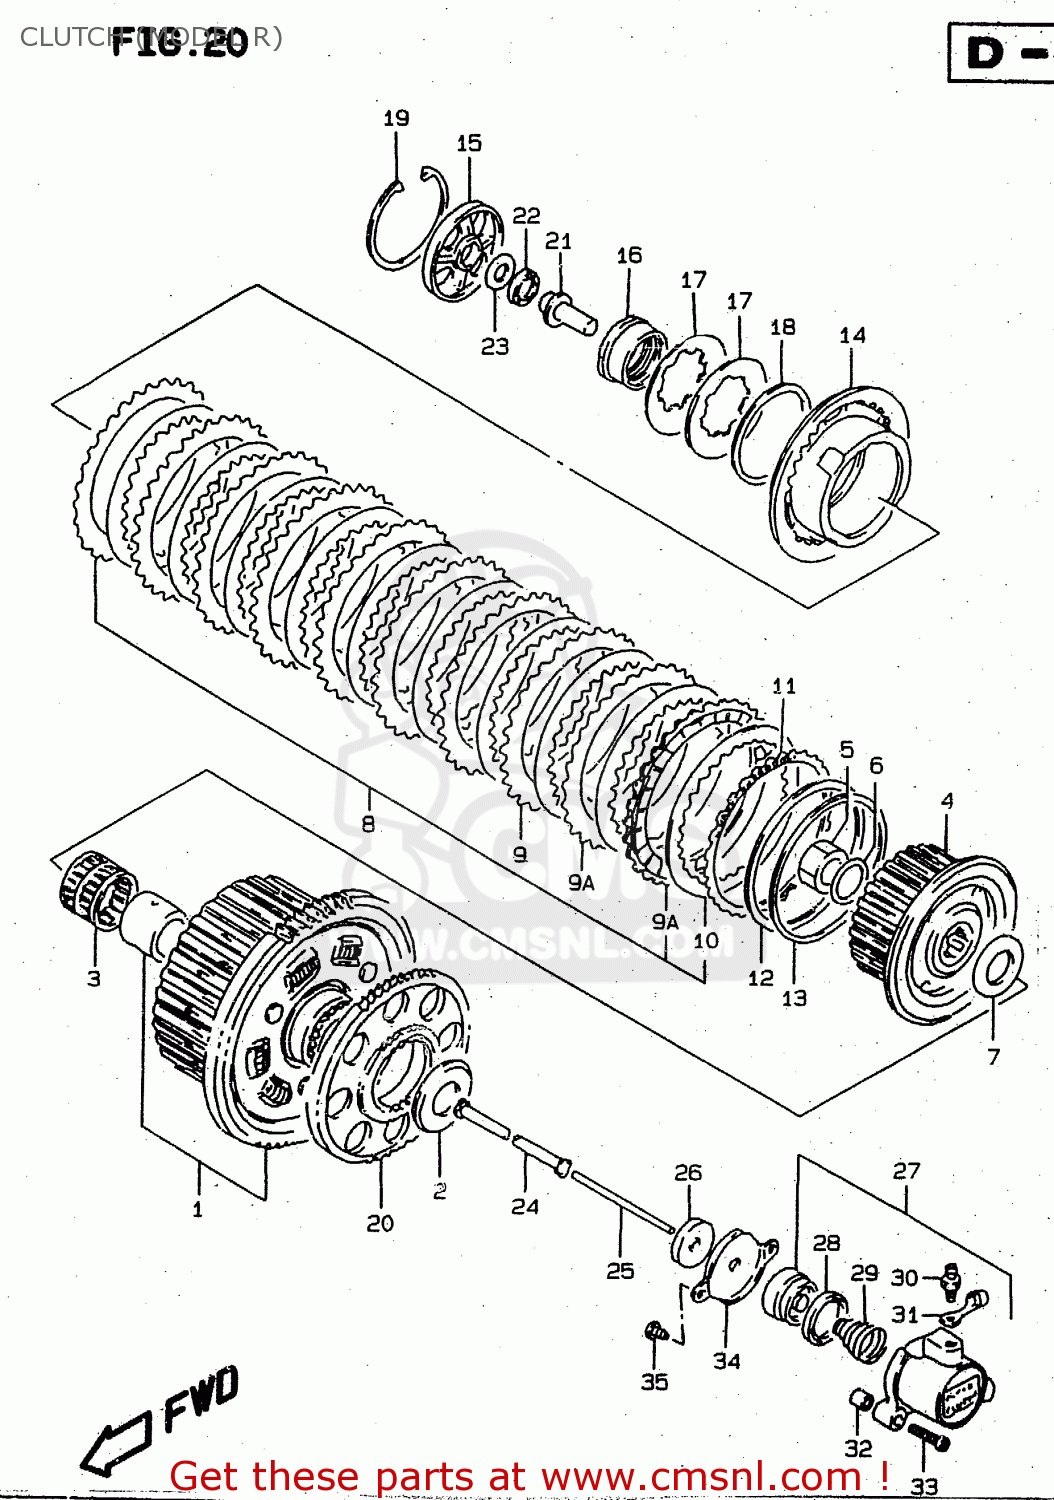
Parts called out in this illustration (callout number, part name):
1	GEAR ASSEMBLY,PRIMARY DRIVE
2	WASHER(25X54X2.5)
3	BEARING(35X40X35.8)
4	HUB,CLUTCH SLEEVE
5	NUT
6	WASHER
7	WASHER(25X50X2.5)
8	PLATE ASSY,CLUTCH
9	PLATE,CLUTCH DRIVE NO.1 (NAS)
9A	PLATE,CLUTCH DRIVE NO.2 (NAS)
10	PLATE,CLUTCH DRIVEN (NAS)
11	PLATE,CLUTCH DRIVE NO.2
12	WASHER
13	SEAT,CL SLEEVE HUB WAVE WASHER
14	DISC,CLUTCH PRESSURE
15	LIFTER,CLUTCH PRESSURE DISC
16	HOLDER,CLUTCH SPRING
17	WASHER
18	SEAT,CLUTCH SPRING
19	CIRCLIP
20	GEAR,GENERATOR DRIVE
21	PIECE,CLUTCH PUSH
22	BEARING(15X28X2)
23	WASHER(15.5X28X1)
24	ROD,CLUTCH
25	ROD,CLUTCH PUSH,L
26	SEAL,OIL(6X34X5.5)
27	CYLINDER,CLUTCH RELEASE
28	CUP
29	SPRING,CLUTCH CYLINDER
30	BLEEDER
31	CAP,BLEEDER
32	PIN
33	BOLT,CL.COVER
34	COVER,CLUTCH RELEASE CYLINDER
35	SCREW
